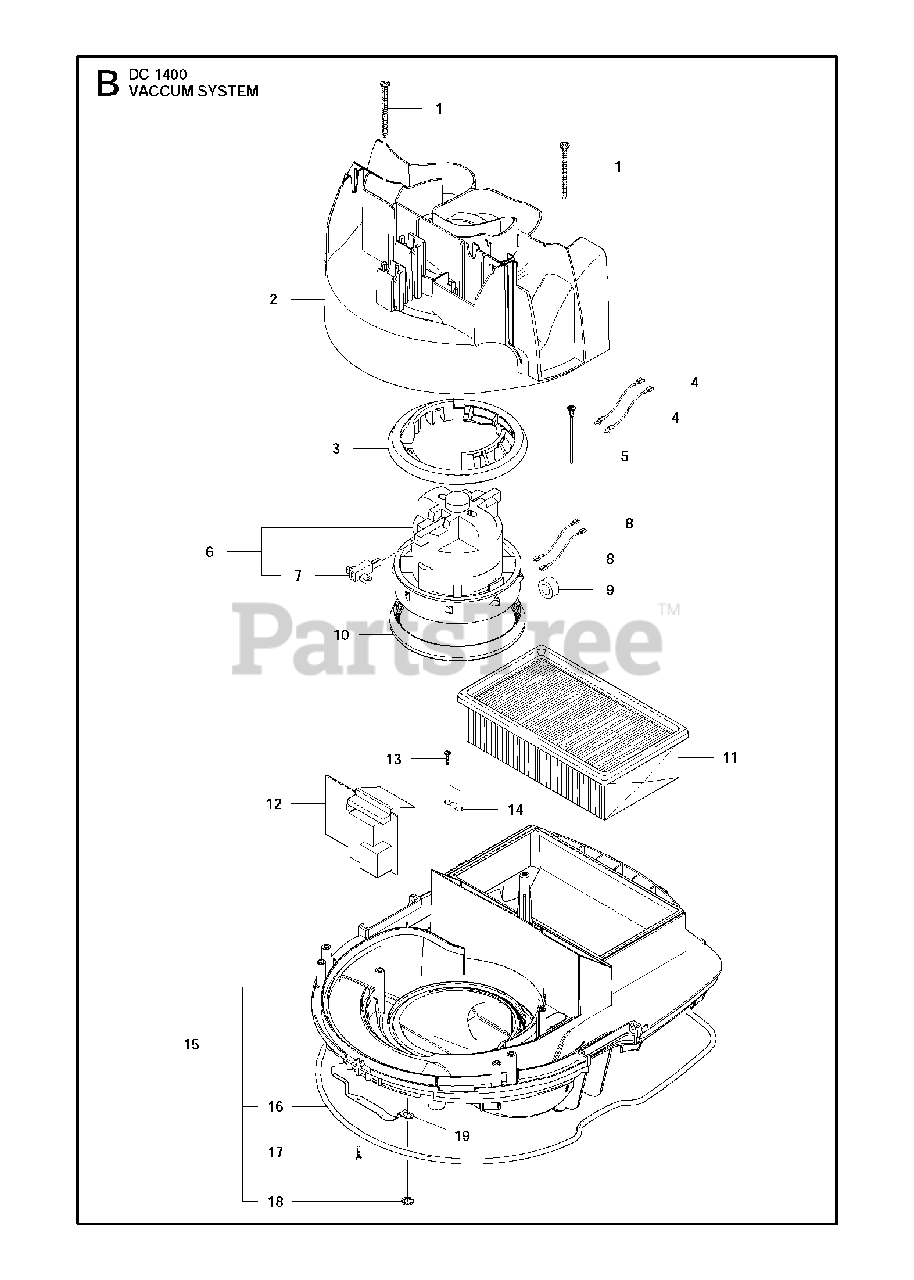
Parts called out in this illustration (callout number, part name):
11	FILTERPES Class M
11	FILTERStandard, paper
11	FILTERClassification HEPA 13
